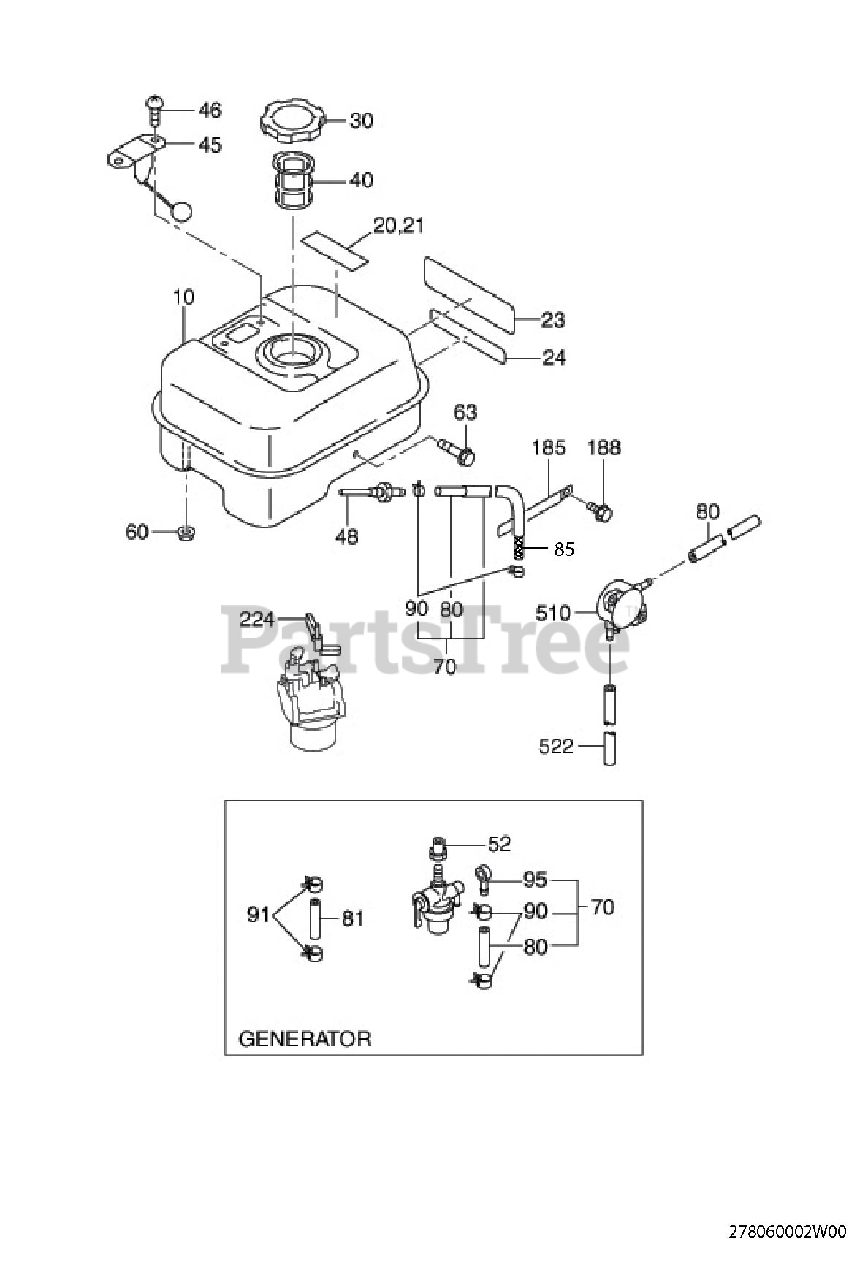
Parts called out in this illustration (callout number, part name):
23	LABEL(TRADE MARK)
30	FUEL TANK CAP CP
48	UNION
60	FLANGE NUT
63	FLANGE BOLT
70	FUEL PIPE CP
80	RUBBER PIPE
85	MESH PROTECTOR
90	HOSE CLAMP
224	CHOKE LEVER CP
